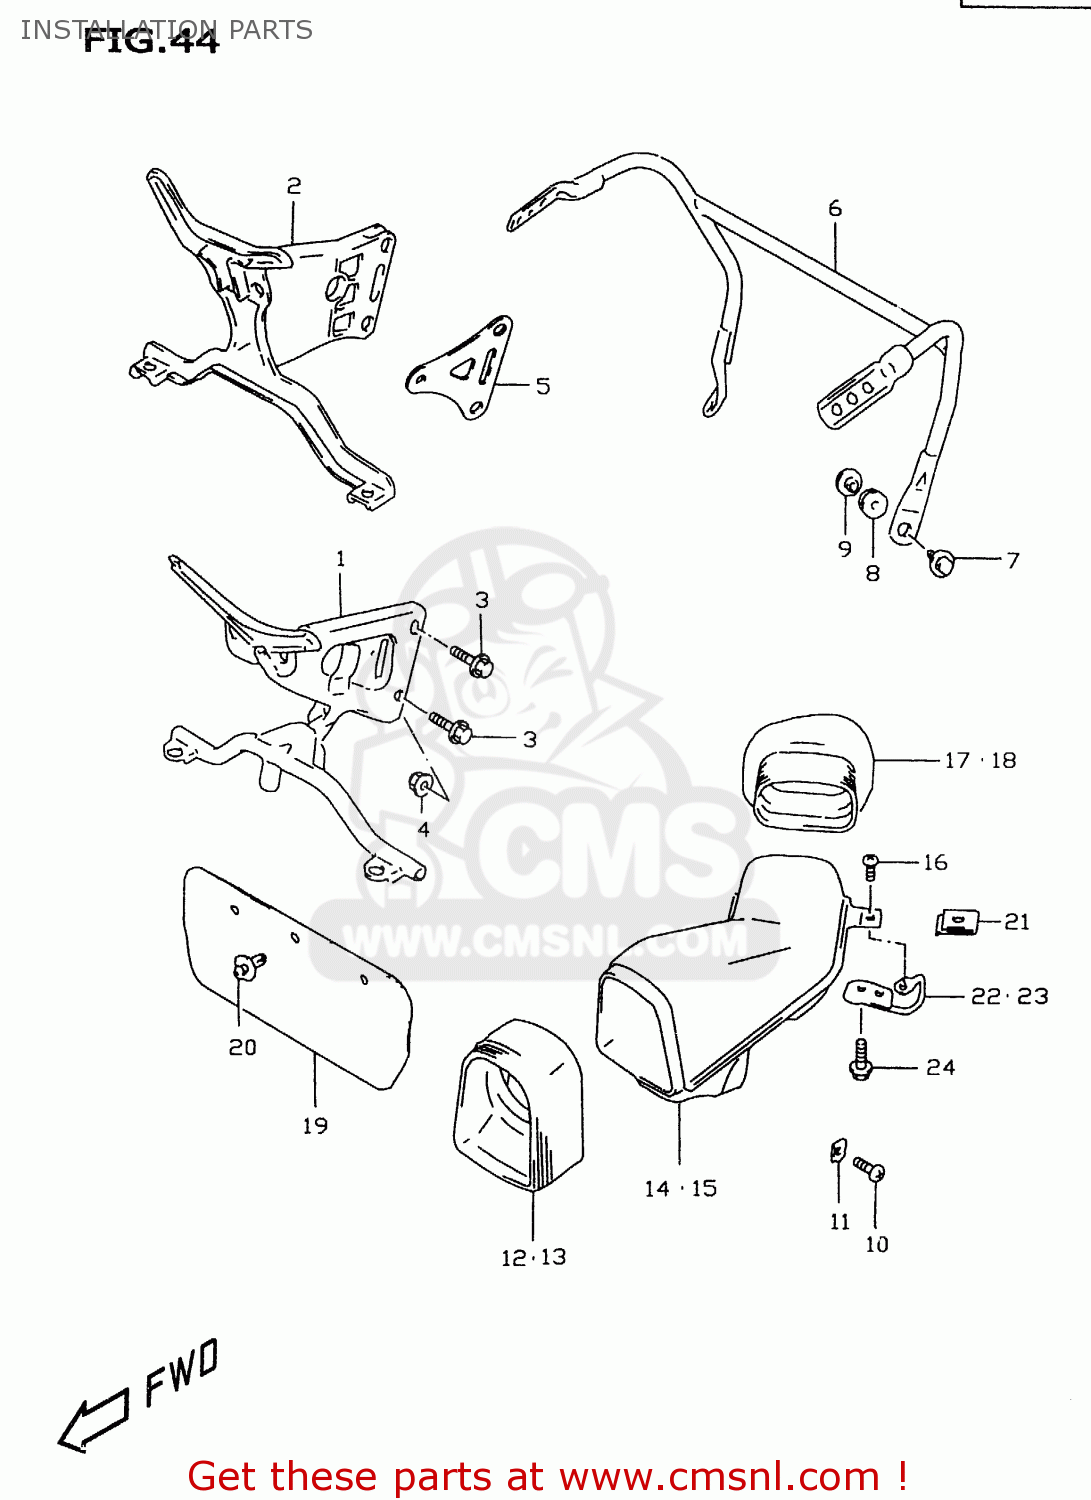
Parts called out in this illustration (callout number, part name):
1	BRACE,COWLING
2	BRACE,COWLING
3	BOLT
4	NUT
5	PLATE,COWLING BRACE
6	BRACE COMP,REAR VIEW MIRROR
7	BOLT(6X25)
8	CUSHION
9	WASHER
10	SCREW(5X16)
11	NUT,HEADLAMP HOUSING,UPPER
12	JOINT,AIR INTAKE,FR,R
13	JOINT,AIR INTAKE,FR,L
14	PIPE COMP,AIR INTAKE,RIGHT
15	PIPE COMP,AIR INTAKE,LEFT
16	SCREW(5X16)
17	JOINT,AIR INTAKE,RR,R
18	JOINT,AIR INTAKE,RR,L
19	PLATE,AIR GUIDE
20	CLIP
21	PLATE,UNDER COWL FITING
22	BRACE,AIR INTAKE PIPE,R
23	BRACE,AIR INTAKE PIPE,L
24	BOLT
